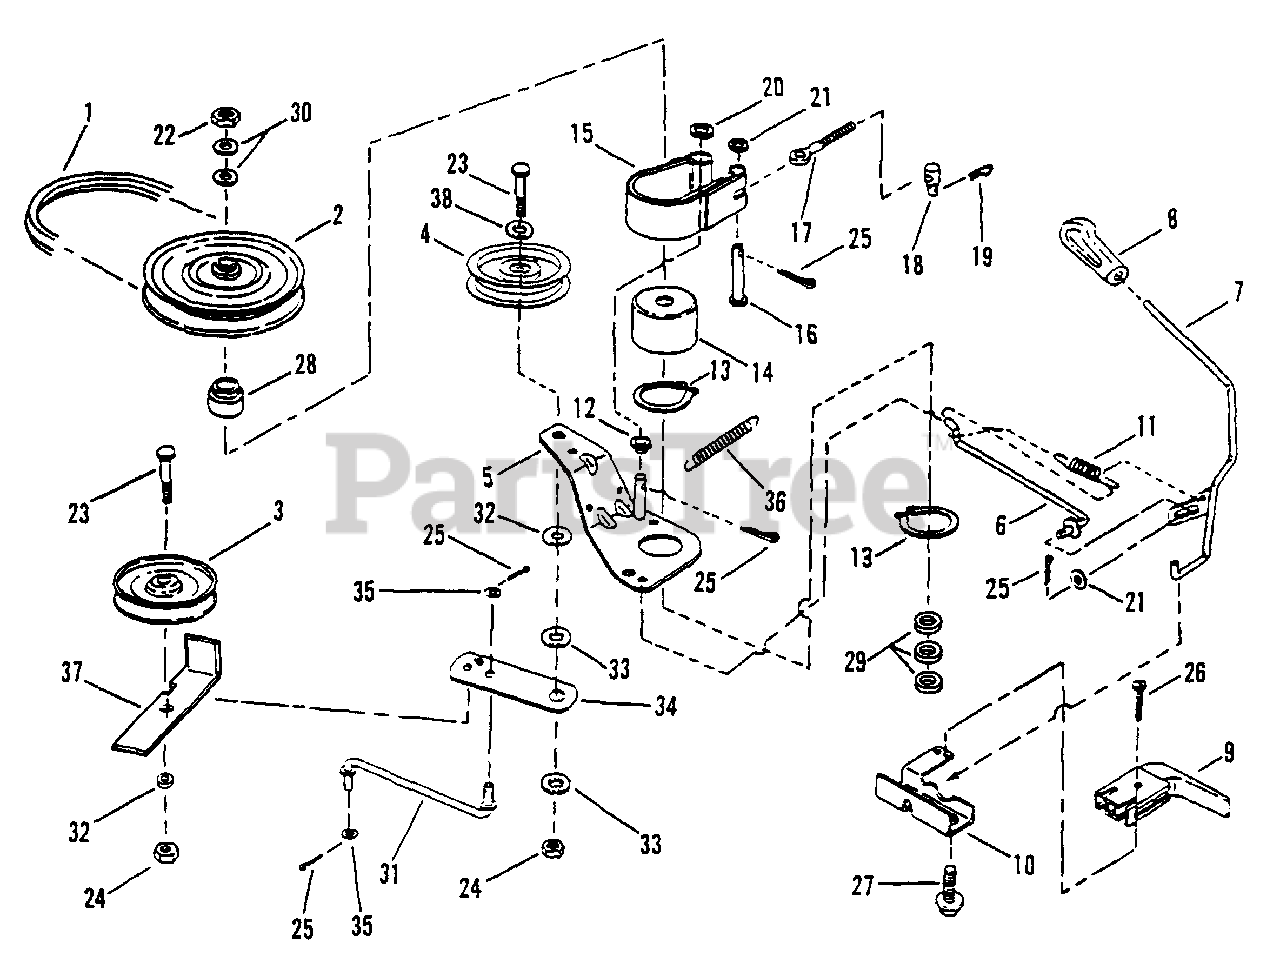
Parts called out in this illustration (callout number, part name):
1	BELT, Drive
2	PULLEY, Spindle
3	PULLEY, 4" Idler
4	IDLER, 4-1/8" Flat
5	ARM, Idler
6	ROD, Idler
7	HANDLE, Blade Lever (On - Off)
8	GRIP, Handle
9	SWITCH, Deck Interlock
10	MOUNT, Handle
11	SPRING, Blade Handle
12	SPACER
13	RING, 2" External Retaining
14	DRUM, Brake
15	BAND, Brake
16	PIN, 1/4 x 1 5/8" Clevis
17	BOLT, 5/16-18 x 3" Eye
18	SWIVEL
19	HAIRPIN, 3/32 x 1-1/2"
20	WASHER, 3/8" Flat
21	WASHER, 1/4 Flat
22	NUT, 3/4-16 Hex Jam
23	SCREW, 5/16-18 x 2" Hex Cap
24	NUT, 5/16-18 Center Lock
25	PIN, 3/32 x 3/4" Cotter
26	SCREW, #10-32 x 1" Self-Tap
27	SCREW, 1/4-20 x 5/8" Self-Tap
28	HUB, Pulley
29	WASHER, Spindle
30	WASHER, 49/64 x 1-1/2" Flat
31	LINK
32	SPACER, 21/64 x 5/8 x 5/32
33	WASHER, 21/64 x 1-1/4 x 3/32
34	LINK, Idler
35	WASHER, 3/8" Flat
36	SPRING
37	RESTRICTOR
38	WASHER
